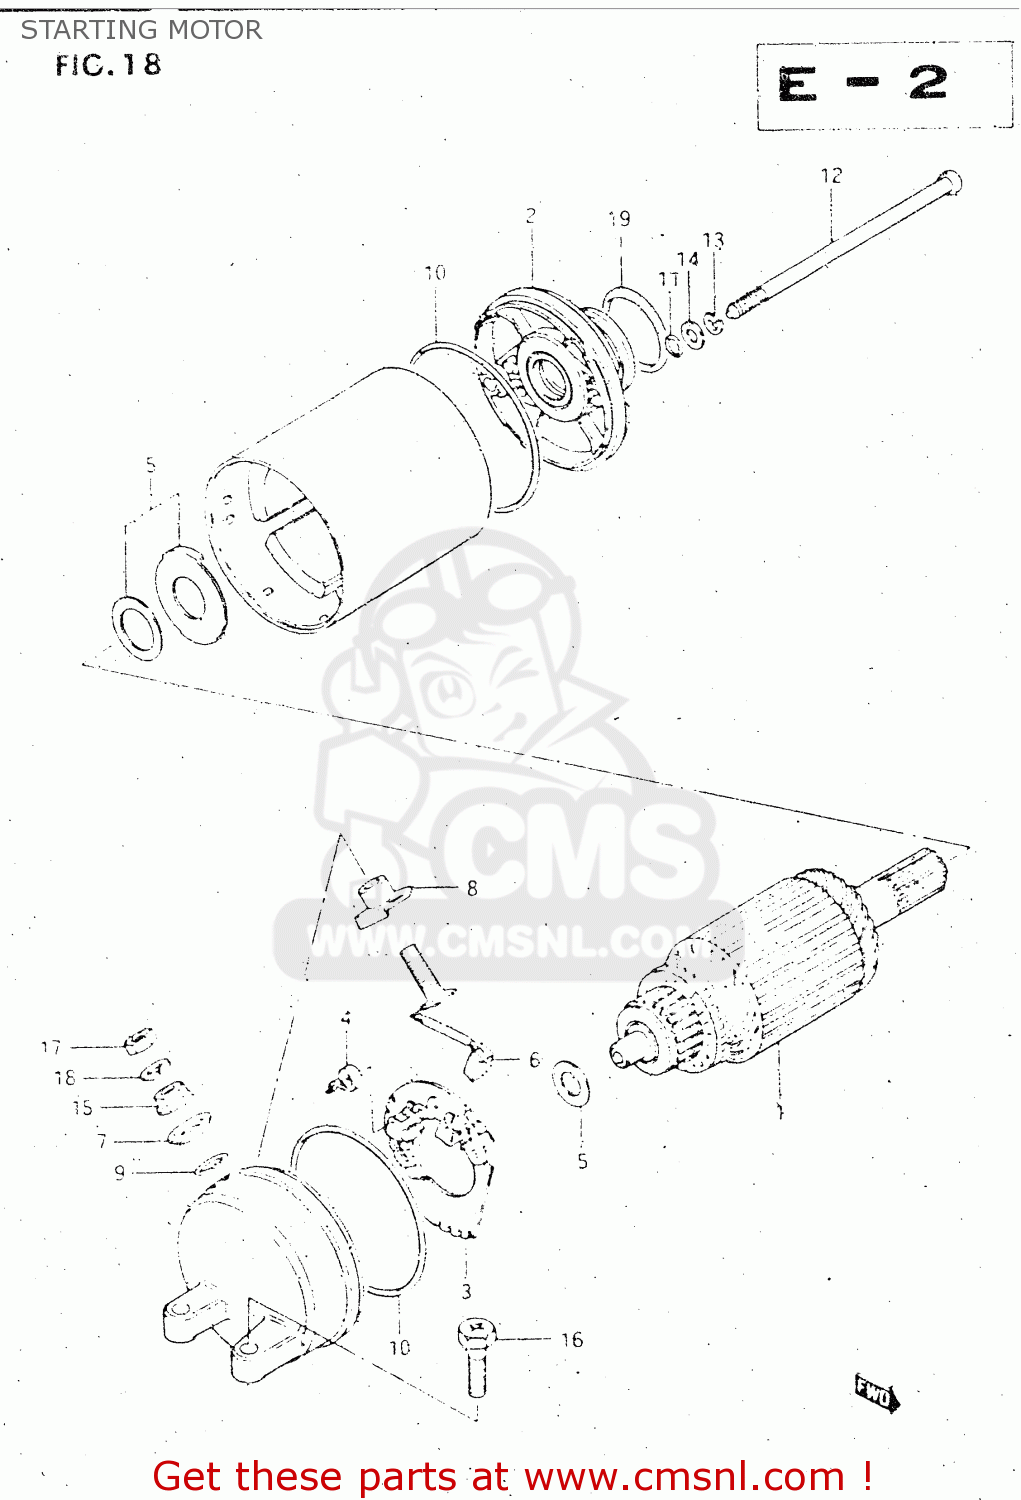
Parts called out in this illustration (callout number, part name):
1	ARMATURE
2	BRACKET SET,STARTING MOTOR
3	HOLDER,BRUSH
4	SPRING
5	SHIM SET,STARTING MOTOR
6	BRUSH SUB ASSY,STARTING MOTOR
7	BUSHING
8	BUSH,B
9	O RING
10	O RING
11	O RING
12	BOLT
13	LOCK WASHER
14	WASHER
15	NUT
16	BOLT
17	NUT
18	WASHER,LOCK
19	O RING(D:3,ID:24.5)
